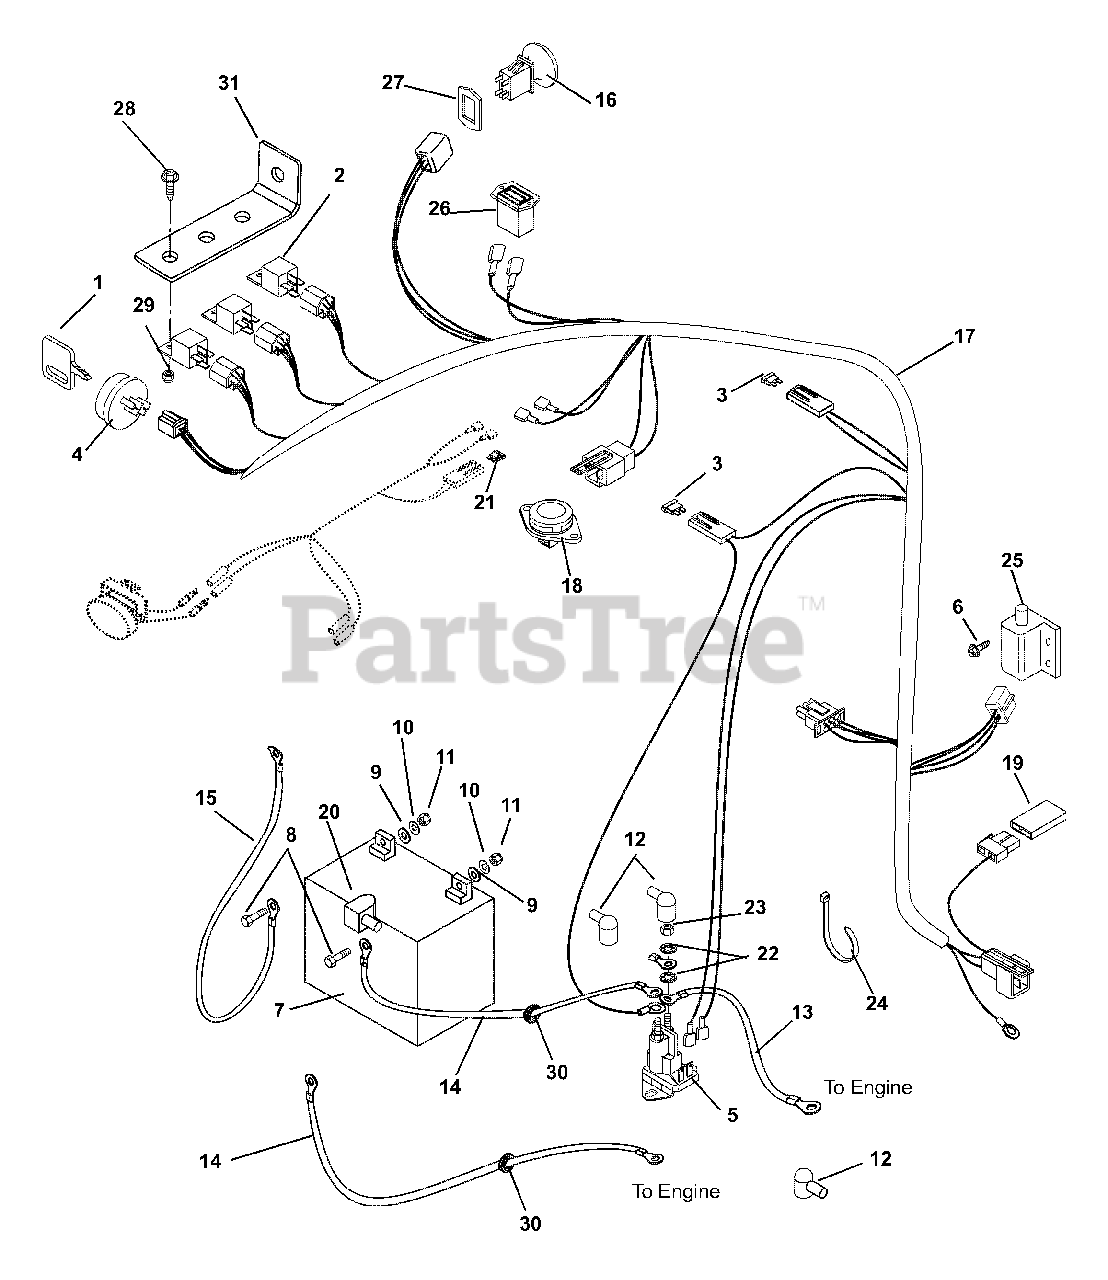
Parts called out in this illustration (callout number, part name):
1	Key with Cap
2	Relay
3	Fuse, 25 AMP
4	Key Switch
5	Solenoid
6	Screw, Tapping 10- 24 x .50 Hex Washer Head
7	Battery, Filled
8	Bolt, Hex .25-20 x .75 Grade 5
9	Washer, Flat Steel .281 x .62 x .065
10	Washer, Locking .25 x .062 Regular
11	Nut, Hex .25-20
12	Boot, Eyelet Terminal
13	Starter Cable 6.75"
14	Starter Cable 16"
14	Starter Cable 22"
15	Ground Cable
16	Switch, Clutch With Retainer
17	Wire Harness, Zoom
18	Switch, Snap Mounting
19	Diode, Connector Shell
20	Insulator
21	Fuse, 20 AMP
22	Washer, Locking .31
23	Nut, Jam .31-24
24	Cable Tie
25	Switch, Double Pole N.O./N.O.
26	Hour Meter
27	Shim, PTO Switch
28	Screw,Machine 10-24 x .50 Slotted Hex
29	Nut-Locking-Nylon 10-24 with Insert
30	Grommet .125 x 1.000 ID
31	Bracket, Relay
